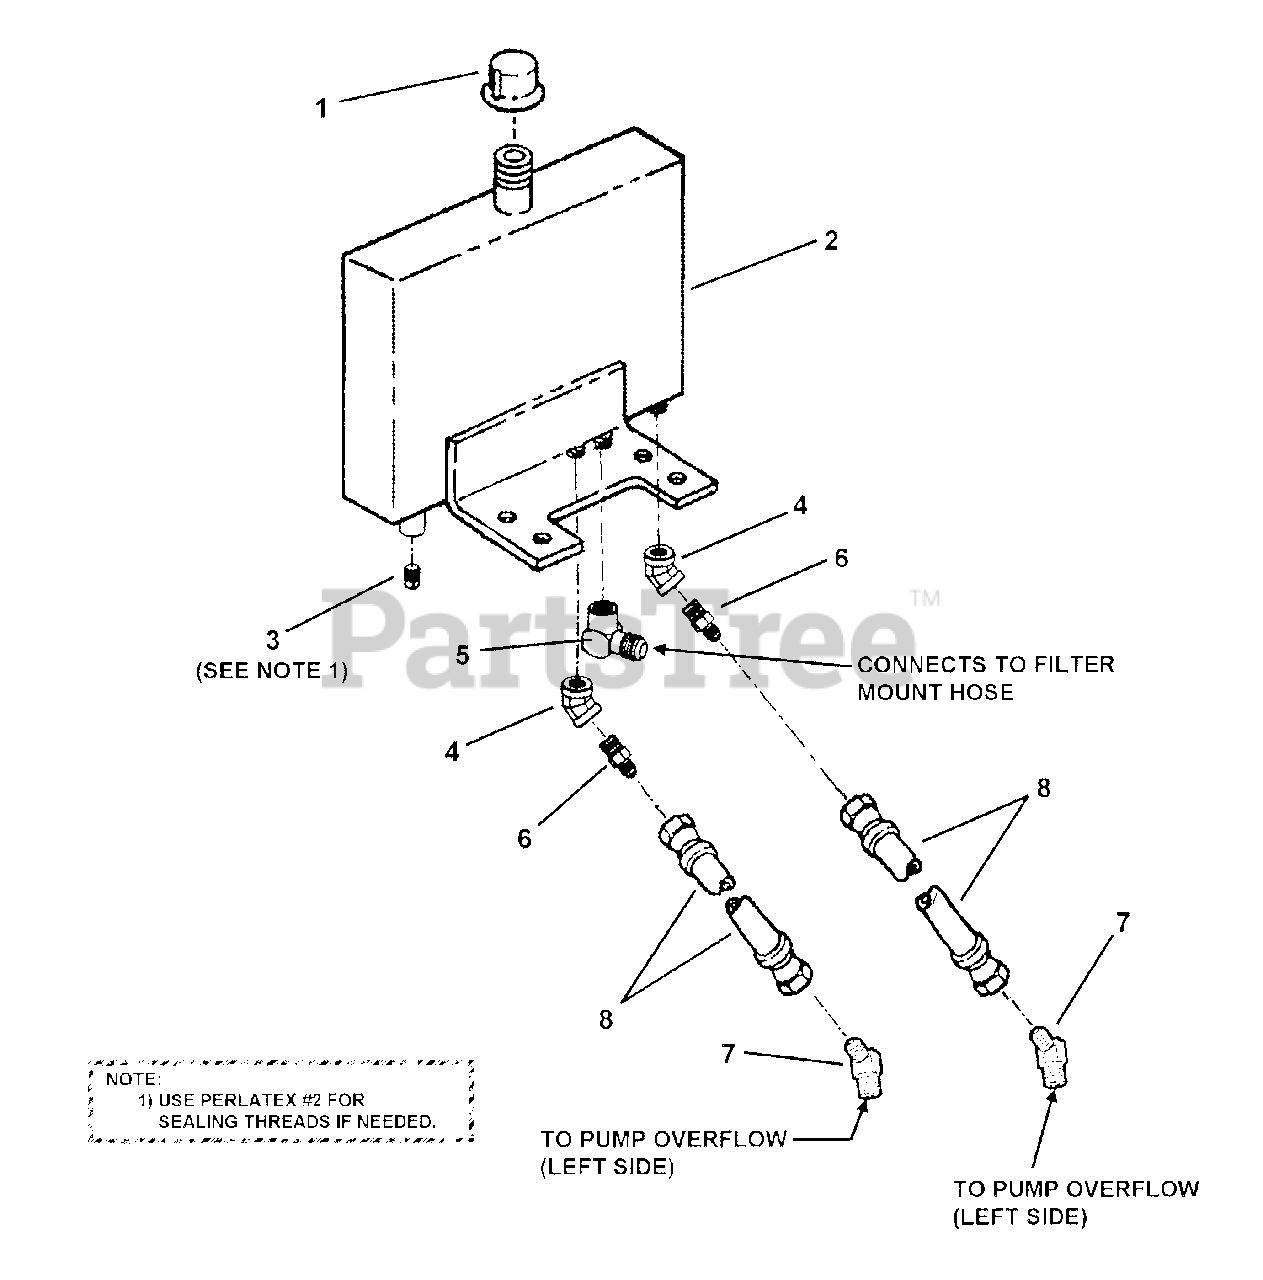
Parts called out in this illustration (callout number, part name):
1	CAP, Hydraulic
2	TANK, Reservoir
3	PLUG, 1/4 NPTM Pipe
4	FITTING, 45 Degree 1/4 FPT Elbow
5	FITTING, 90 Degree
6	FITTING, Straight 1/4
7	FITTING, External 45 Degree w/37 Degree Flare
8	HOSE, 10-1/2" Long (7/16-20 Female Thread)
